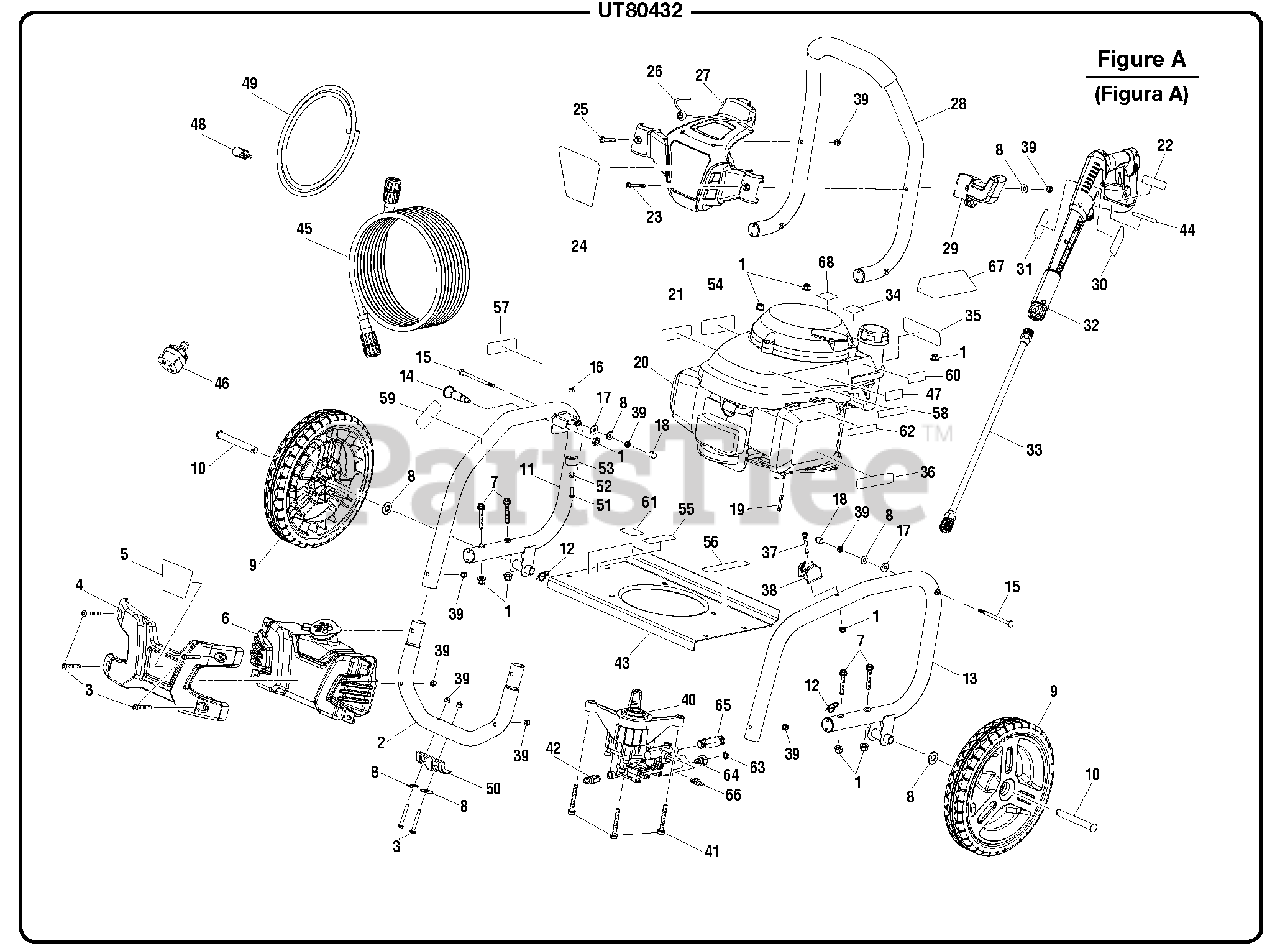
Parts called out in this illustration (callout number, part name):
1	Lock Nut (M8 x 1-1/4 in.)
2	Front Frame
3	Screw (1/4-20 x 2 in.)
4	Detergent Tank Cover
5	Logo Label (Homelite)
6	Detergent Tank
7	Bolt (M8 x 55 mm)
8	Washer (1/4 in.)
10	Axle
11	Main Frame Assembly (right)
12	Spring pin
13	Main Frame Assembly (left)
14	Handle Release Knob
15	Bolt (1/4-20 x 3.5 in.)
16	Flange Nut (M4 x 0.7)
19	Output Shaft Key
21	Hot Surface Label
22	Trigger Handle Warning Label
23	Screw (1/4-20 x 2.27 in.)
24	Performance Label
25	Screw (1/4-20 x 1.65 in.)
26	Bungee Cord Assembly
27	Hose Storage
28	Handle Assembly
29	Trigger Handle Holder
30	Trigger Handle Warning Label
31	Logo Label
32	Trigger Handle Assembly
33	Spray Wand
34	E85 Label
35	Danger Label
36	Engine Quick Start Label
37	Bolt (1/4-20 x 1.85 in.)
38	Spray Wand Holder
39	Lock Nut (1/4-20)
40	Pump (Incl. Key Nos. 41-42)
41	Bolt (M8 x 60 mm)
42	Thermal Release Valve
43	Engine Plate
44	Trigger Handle Spec Label
45	High Pressure Hose (25 ft.)
46	6-in-1 Change Over Nozzle
47	Release Water Label
49	Injection Hose
50	Rubber Foot
51	Bolt (M4 x 12.5 in.)
52	Washer (M4)
53	Rubber Bumper
54	Danger Label (French)
55	Data Label
56	Pump Quick Start Label
57	Combustion Warning Label
58	EMC Label
59	Hot Surface Label
60	Choke Label
61	Oil Dipstick Label
62	Inquiries Label
63	Filter Screen
64	Inlet Tube
65	Outlet Tube
66	Detergent Suction Kit
67	Warning Hang Tag
68	Lubricant Label
